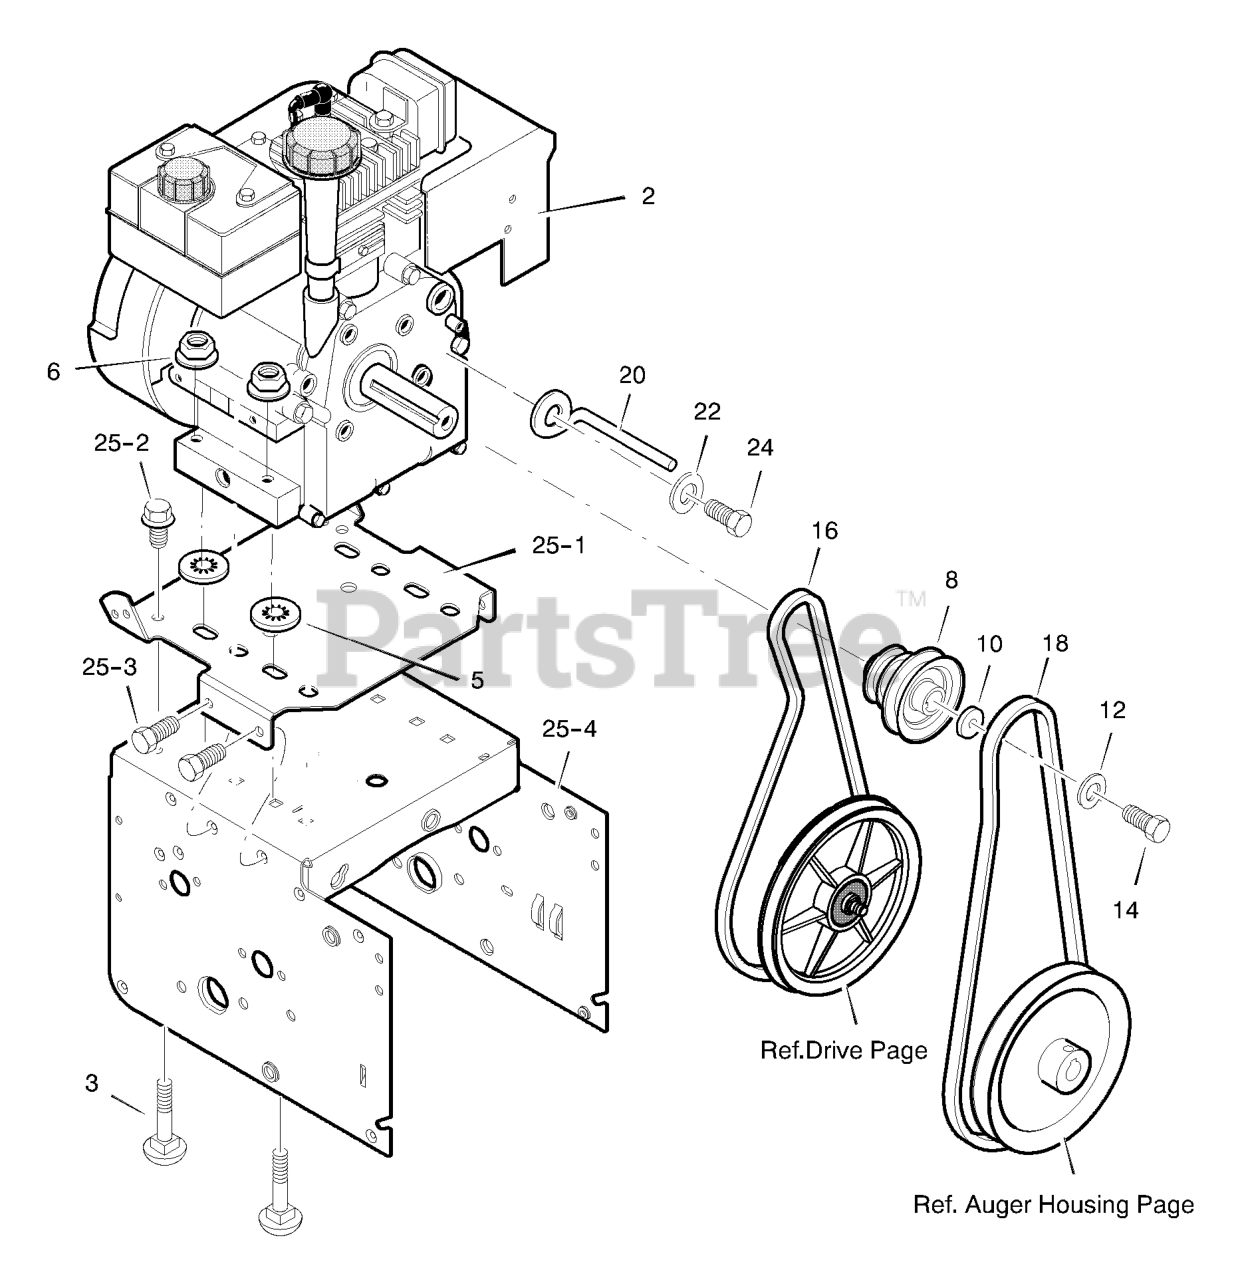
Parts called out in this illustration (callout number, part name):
2	ENGINE
3	BOLT, CARRIAGE 5/16-18
5	RETAINER, PUSH
6	NUT, HEXWDFLLK 5/16-18
8	PULLEY, ENGINE
10	WASHER
12	WASHER .38ID
14	SCREW, 3/8-24 x 1.00
16	BELT, V 3L 33.13LG
18	BELT, V 4L35.6 LG
20	GUIDE, BELT
22	WASHER, SPTLK .31X.58X.08
24	SCREW, 5/16-24 x 0.75
25	FRAME, MOTORBOX
25-1	PLATE, ENGINE MOUNT
25-2	SCREW, TAP 1/4-20 X .63
25-3	SCREW, TAP 5/16-18 X .50
25-4	FRAME, MOTOR BOX
